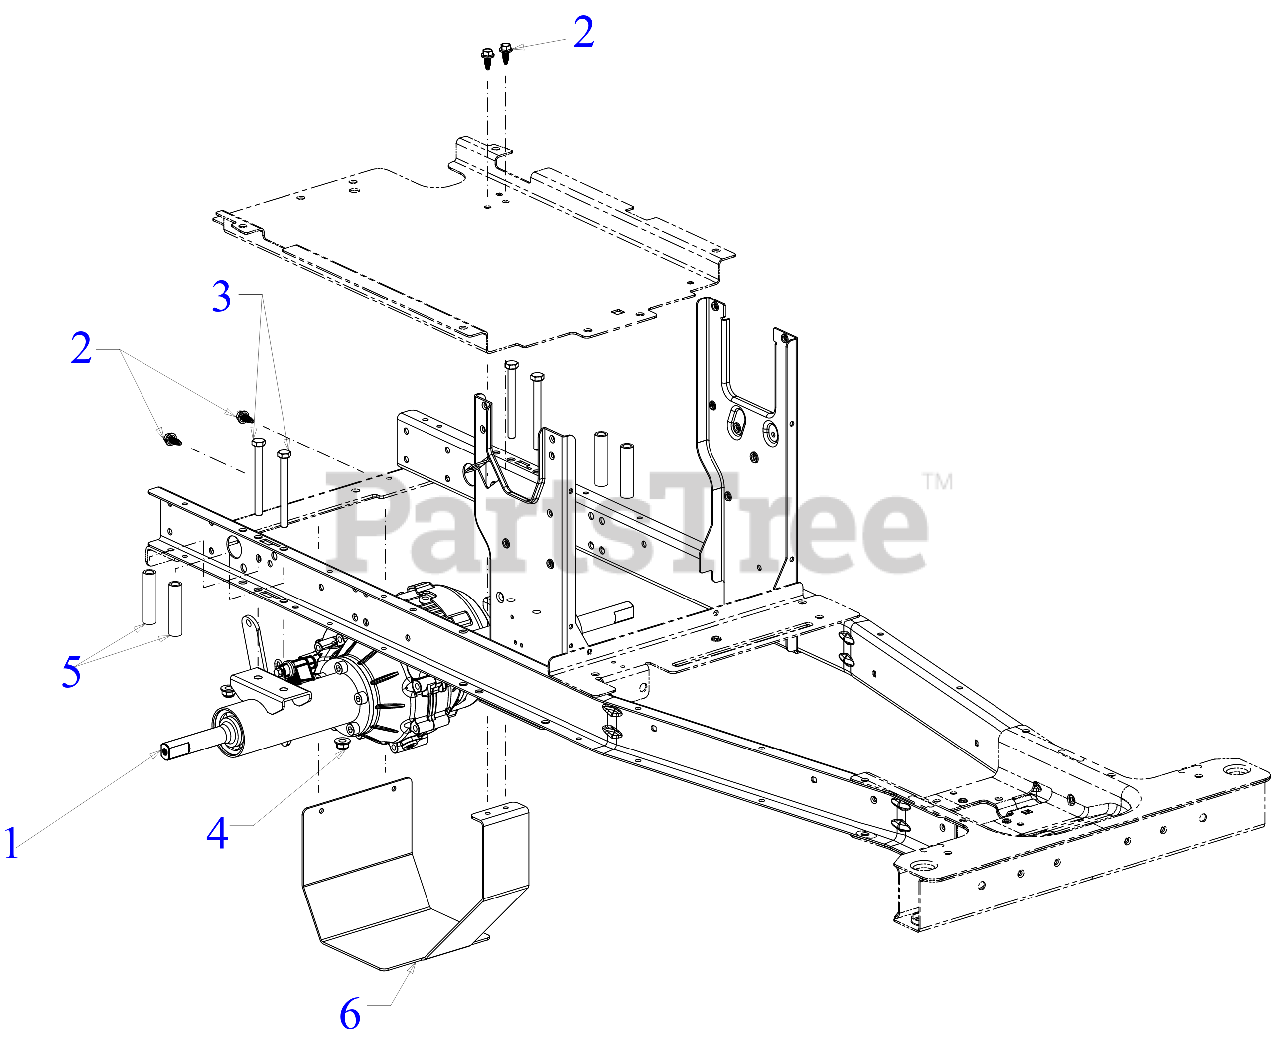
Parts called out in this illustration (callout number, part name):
1	TRANSMISSION ASSEMBLY
2	SCREW 1/4-20X.625
3	SCREW 5/16-18 x 3.25 GR5
4	FLANGE LOCK NUT 5/16-18
5	SPACER (.35 x .55 x 2.345)
